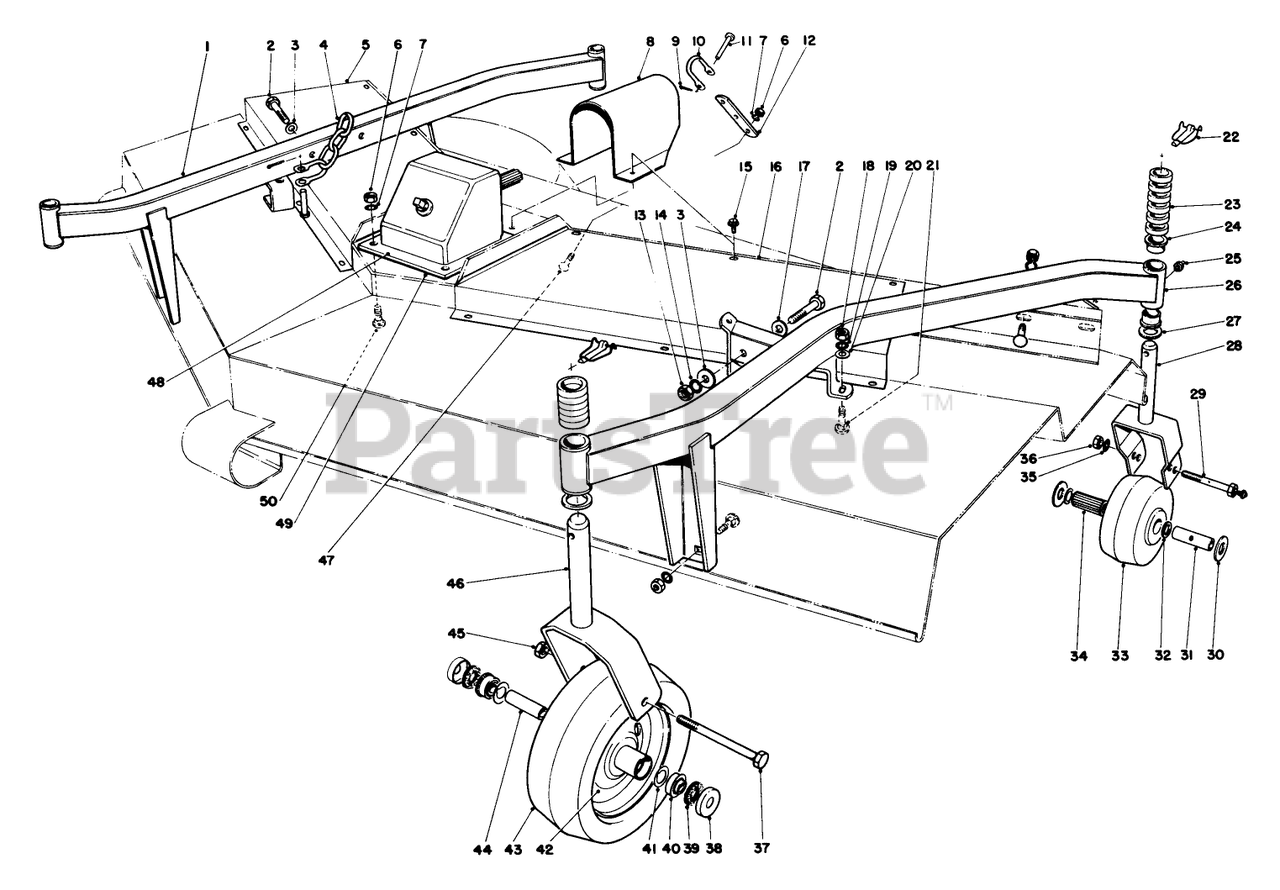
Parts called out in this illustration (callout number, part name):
1	Caster Arm R.H. (Incl. Ref. #24)
2	SCREW-HH
3	WASHER-FLAT
4	Lift Chain
5	RH DECK COVER R
6	NUT-HEX
7	WASHER-LOCK
8	Shroud Universal
9	PIN-COTTER
10	SHACKLE
11	PIN-CLEVIS
12	Lift Strap
13	NUT-HEX
14	WASHER-LOCK
15	SCREW-HHF
16	LH DECK COVER R
17	WASHER-FLAT
18	NUT-HH
19	WASHER-LOCK
20	WASHER-FLAT
21	SCREW-CARR
22	PIN-LYNCH
23	SPACER 1/2 IN
24	Bushing
25	FITTING-GREASE
26	LH CASTOR ARM ASM
27	WASHER-THRUST
28	Caster Fork Rear
29	AXLE ASM
30	WASHER-FLAT
31	SPANNER BUSHING
32	Bearing Retainer Seal
33	WHEEL
34	ROLLER BRG W/46-8960
35	WASHER-LOCK/INT
36	NUT-JAM
37	Screw
38	AXLE SLINGER B
39	WASHER
40	.500 RF BALL BEARING
41	WASHER
42	Castor Wheel & Tire (Incl. ref . #43)
43	Tire
44	SPACER
45	NUT-HEX
46	Caster Fork
47	SCREW-CARR
48	GEAR BOX ASM
49	SPACER R
50	SCREW-CARR
